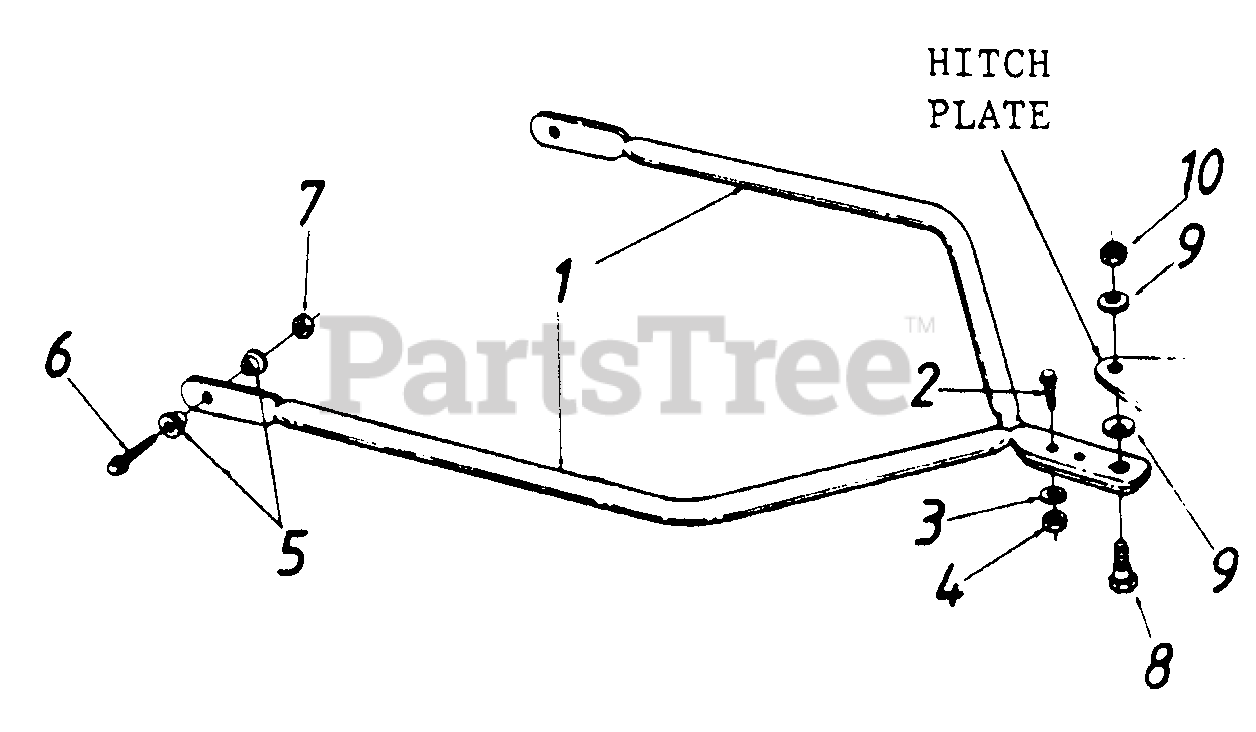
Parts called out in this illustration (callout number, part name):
3	L.-Wash. 1/4" I.D.
4	Hex Nut 1/4-20 Thd.
5	Shoulder Spacer
6	Hex Wash. Hd. Self-Tapp Scr. 5/16-18 x 1.0" Lg.
7	Hex Nut 5/16-18 Thd.
8	Shoulder Bolt
9	Bell-Wash. .39" I.D. x 1.12"
10	Hex Top Jam Nut 3/8-16 Thd.
